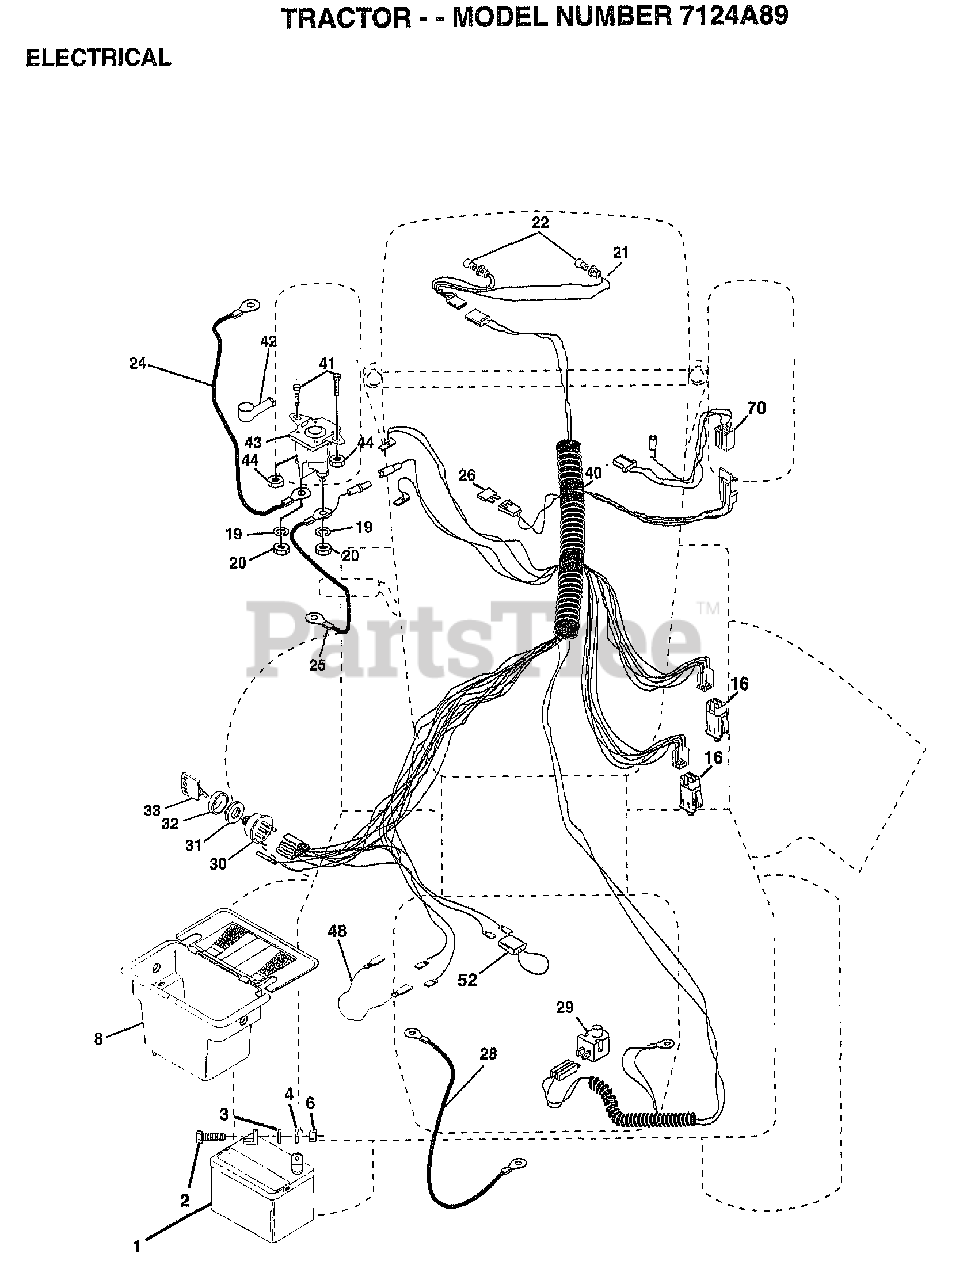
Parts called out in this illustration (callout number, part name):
2	BOLT LT
3	WASHER
4	LOCKWASHER
8	"CASE,BATTERY.MECH"
16	SWITCH INTERLOCK
20	NUT
21	"HARNESS,LIGHT SOC"
22	HEADLAMP BULB
24	"CABLE T, BATTERY"
25	CABLE.BTRY.6GA.RD
26	FUSE HYT
28	CABLE T
29	SWITCH SEAT
30	SWITCH IGN 4POS
31	NUT IGNITION
32	COVER KEY SWITCH
33	KEY
40	HARNESS-IGNITION
41	BOLT HXHD FIN
44	NUT HXKEP 1/4X20
48	ADAPTER AMMETER
52	PROTECTION LOOP
70	HARNESS ENG DUAL
